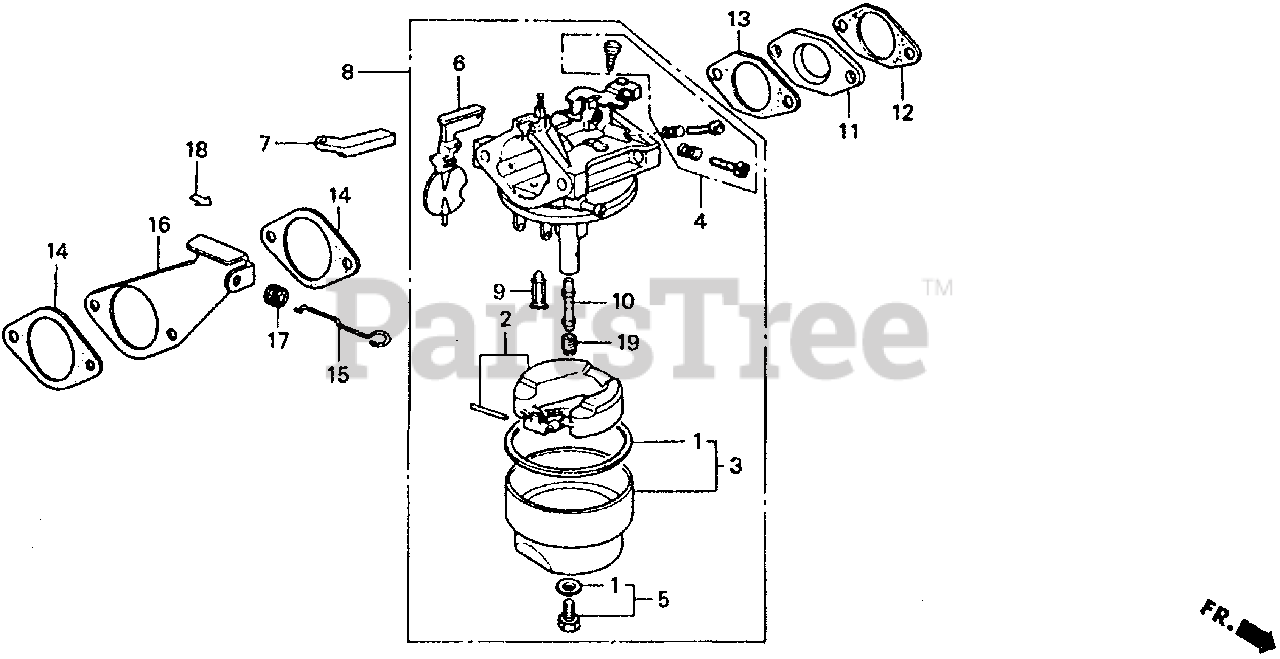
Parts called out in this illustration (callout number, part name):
1	GASKET SET
2	FLOAT SET
3	CHAMBER SET, FLOAT
4	SCREW SET A
5	SCREW SET B
6	CHOKE SET
7	ARM, CHOKE LEVER
8	CARBURETOR ASSY.
9	VALVE, FLOAT
10	NOZZLE, MAIN
11	INSULATOR, CARBURETOR
12	GASKET, INSULATOR
13	GASKET, CARBURETOR
14	GASKET, AIR CLEANER
15	ROD, CHOKE CONTROL
16	STAY, CHOKE CONTROL
17	GROMMET, CHOKE ROD
18	MARK, CHOKE
19	JET, MAIN (#55)
19	JET, MAIN (#58)
19	JET, MAIN (#60)
19	JET, MAIN (#62)
19	JET, MAIN (#65)
